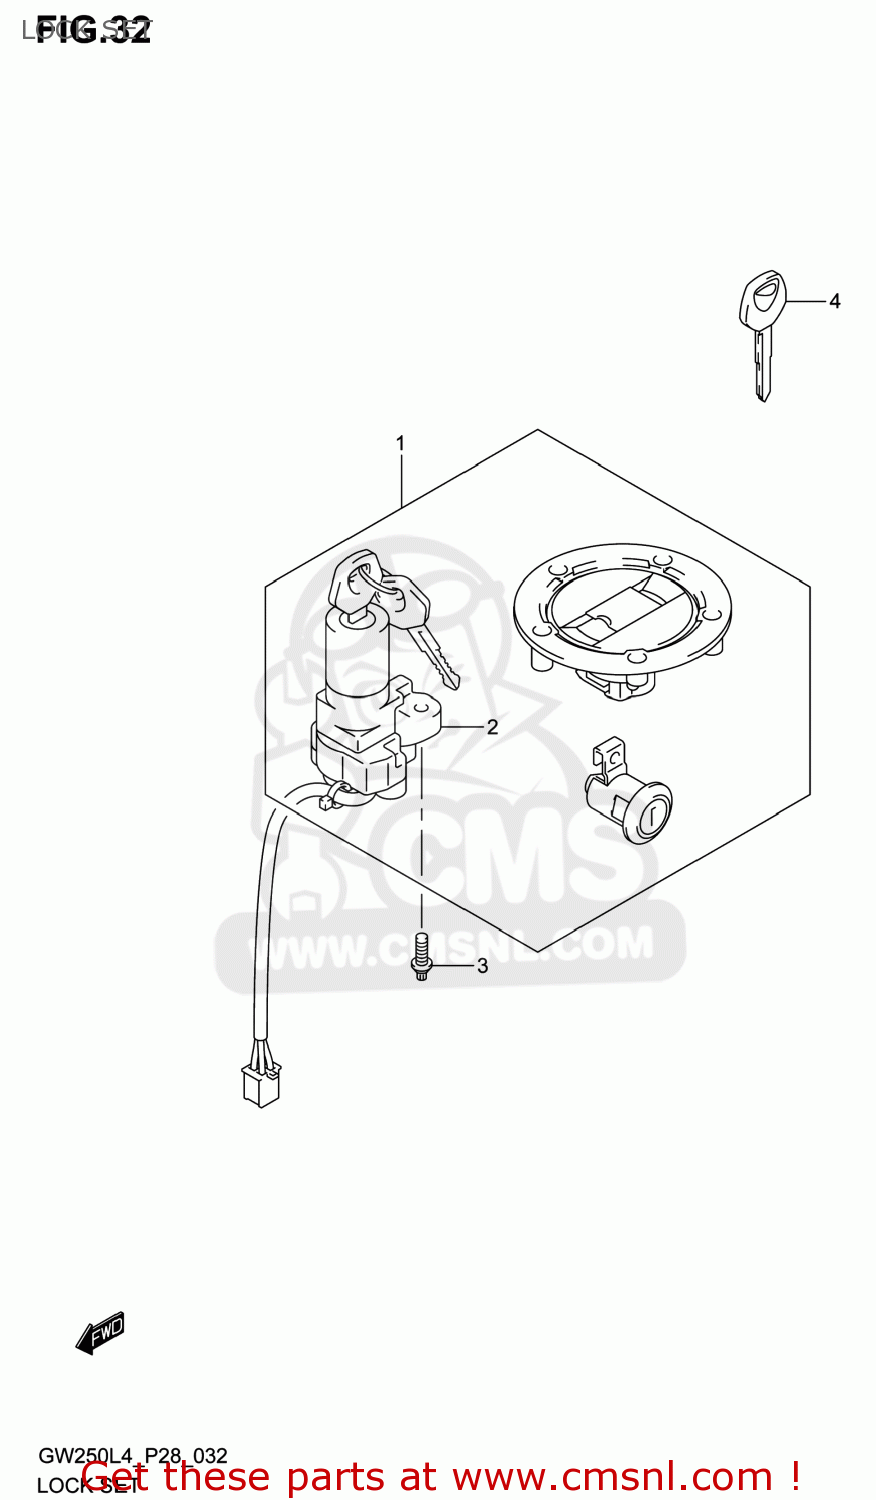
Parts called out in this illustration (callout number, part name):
1	LOCK SET
2	LOCK ASSY,STEERING
3	SCREW(6X18)
4	KEY,BLANK
